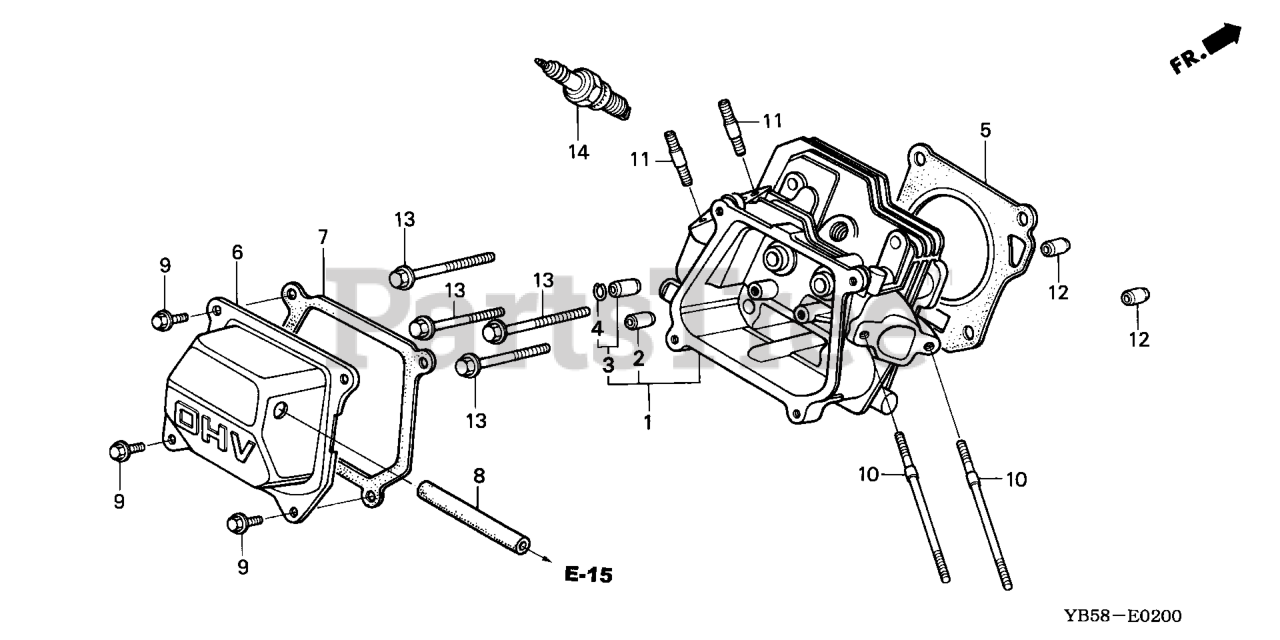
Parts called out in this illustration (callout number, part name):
1	CYLINDER HEAD
2	GUIDE, VALVE (OVER SIZE) Use from Engine SN 6324986.
4	CLIP, VALVE GUIDE Use from Engine SN 1231803.
5	GASKET, CYLINDER HEAD
6	COVER, HEAD
7	GASKET, CYLINDER HEAD COVER
8	TUBE, BREATHER
9	BOLT, FLANGE (6X12) (CT200)
10	BOLT, STUD (6X109)
11	BOLT, STUD (8X32)
12	PIN A, DOWEL (10X16)
13	BOLT, FLANGE (8X60)
14	SPARK PLUG (BPR6ES) (NGK)
14	SPARK PLUG (W20EPR-U) (DENSO)
